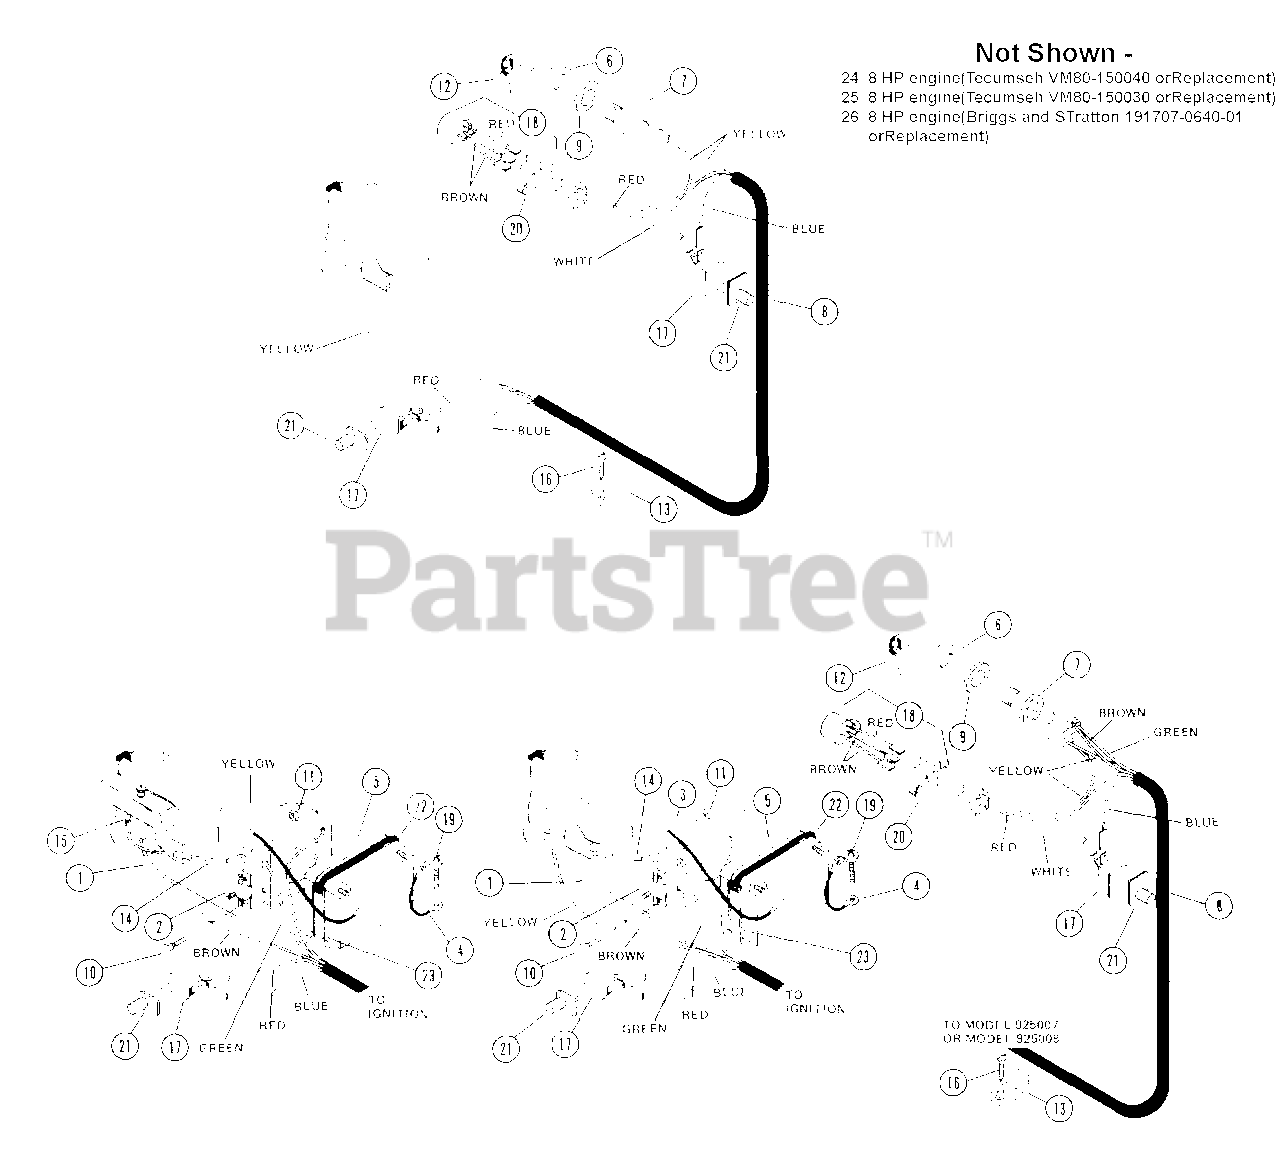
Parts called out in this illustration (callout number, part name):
1	GROUND CABLE
1	GROUND CABLE .25X13.00X.31
2	SOLENOID
3	GROUND CABLE
4	GROUND WIRE
5	BATTERY
6	NUT .625-32 ALUM
7	IGNITION SWITCH ASSEMBLY
7	KEY SWITCH ASSEMBLY
8	WIRING HARNESS
9	WSHR-LK-INT .625X.045 PL
10	BLT-HEX .25-20X.75 PL GR5
11	NUT-LK-CTR .250-20 PL
12	KEYS
13	CLIP
14	CHARGING WIRE
15	FUSE
16	SCR-TAP 8-15X.38 CR RH A
18	MODULE ASSEMBLY
19	SCR-TAP 10-24X.375 CRPH 1A
20	SHIFT LINK
21	SWITCH BOOT
22	BATTERY STRAP
23	HOOK
24	8 HP engine(Tecmuseh VM80-150040 orreplacement)
25	8 HP engine(Tecumseh VM80-150030 orreplacement)
26	8 HP engine(Briggs and Stratton 191707-0640-01 or replacement)
